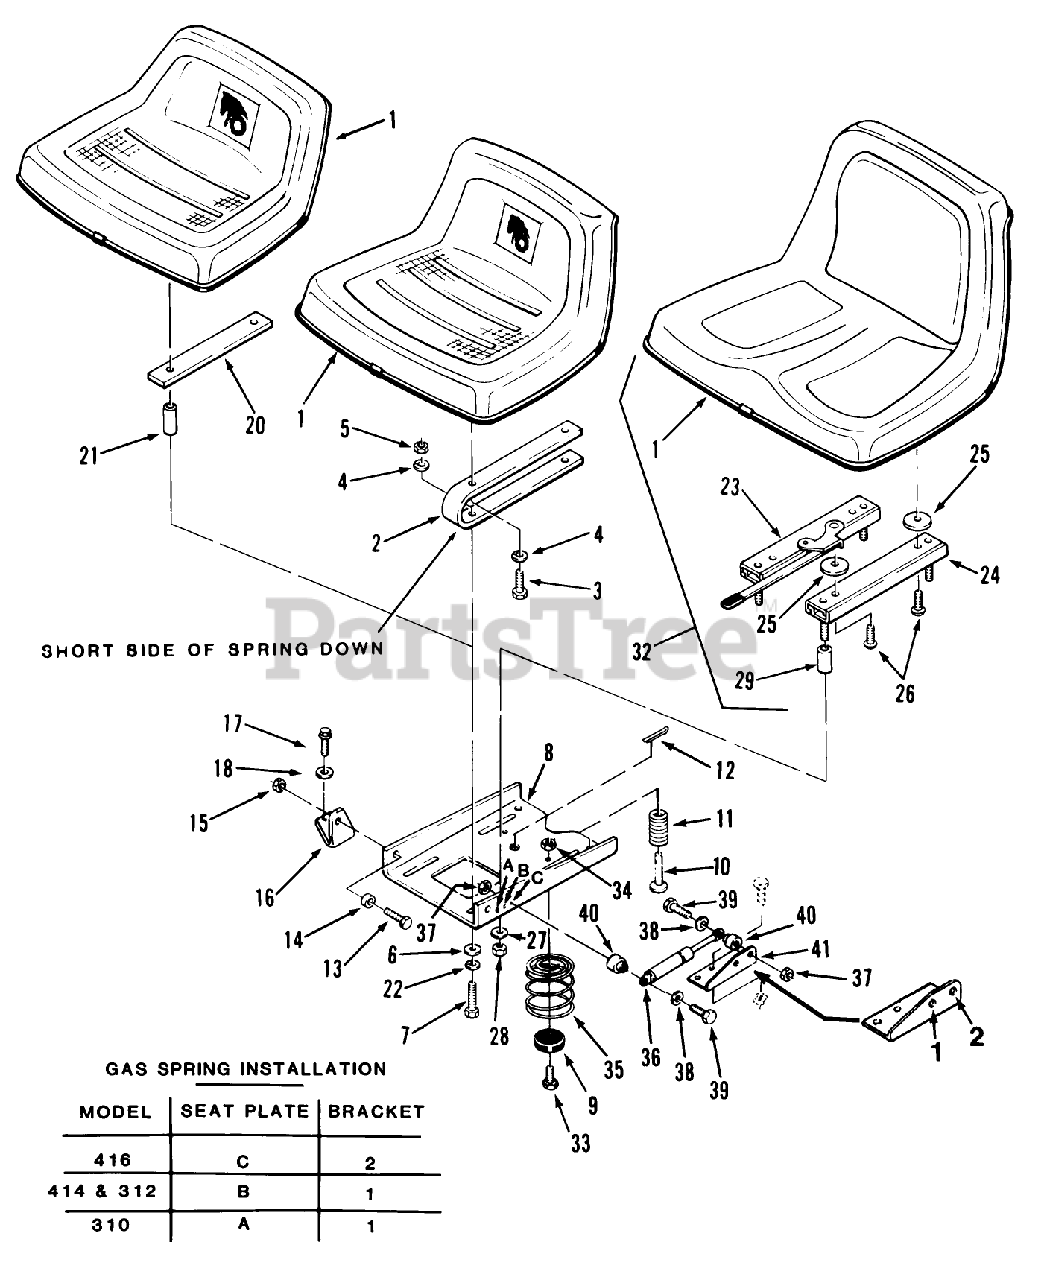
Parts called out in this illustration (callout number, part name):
6	WASHER 5/16 SAE
9	BUMPER
11	SPRING-SEAT SWITCH
14	BUSHING
16	BRACKET-PIVOT R.H *B (NS)
18	WASHER 5/16 SAE
21	SPACER SEAT *B
25	SPACER-NYLON
31	SPRING SWITCH
35	SPRING-SEAT NYLON
36	GAS SPRING
40	SPACER
41	BRACKET-CYLINDER *R
